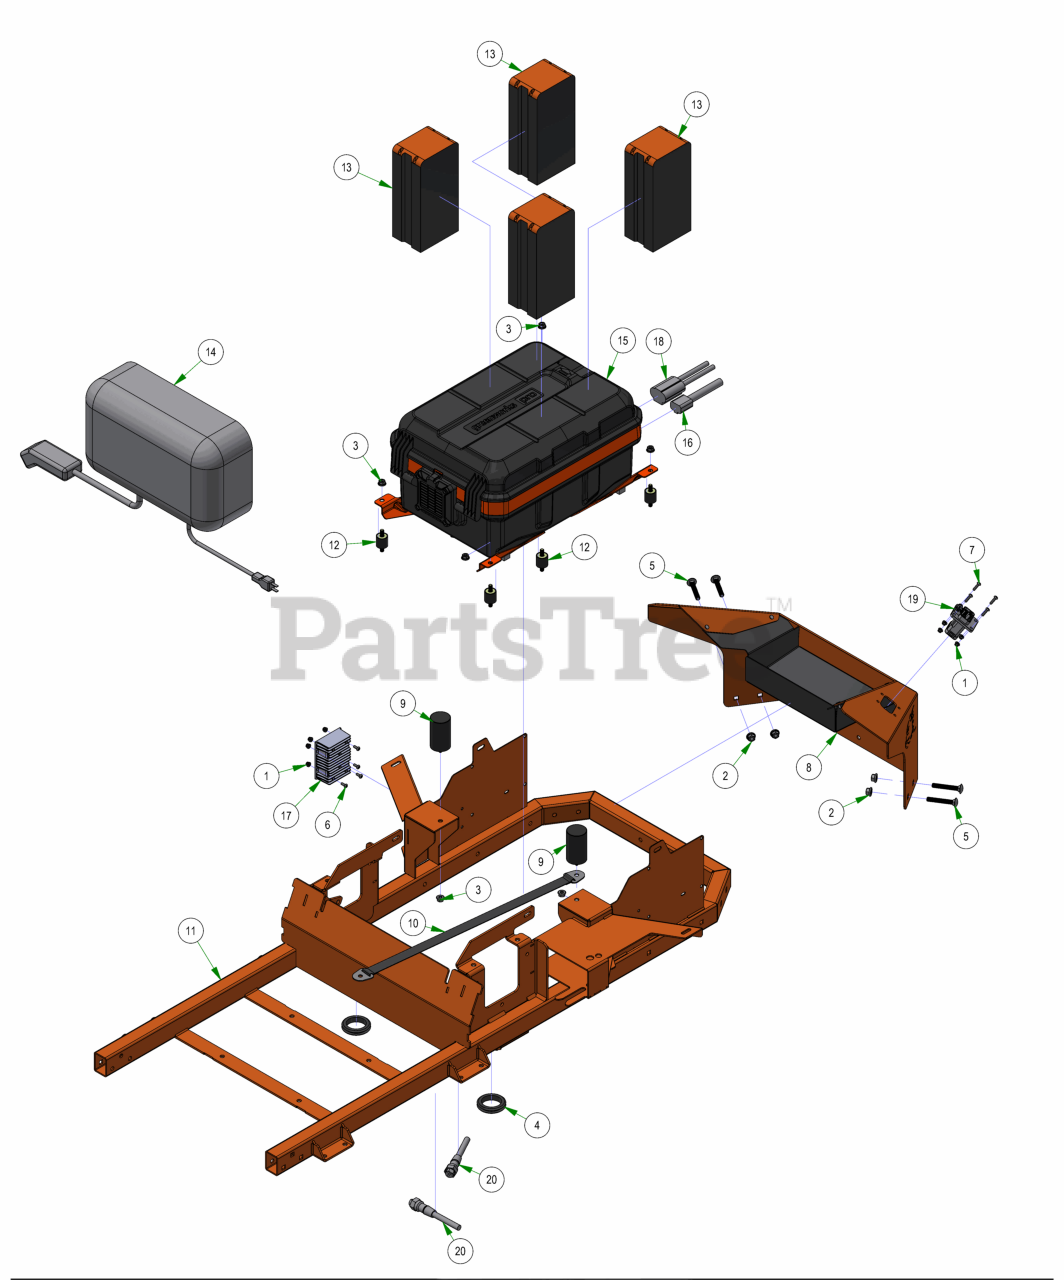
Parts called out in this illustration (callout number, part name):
1	10-24 NYLON INSERT LOCKNUT ZINC
2	3/8-16 NYLON INSERT FLANGE LOCKNUT (GR.F) ZINC
3	5/16-18 NYLON INSERT FLANGE LOCKNUT ZINC
4	2019 2" x .25 Rubber Grommet
5	3/8" x 2 1/2" Carriage Bolt
6	10-24 X 1/2 BUTTON SOCKET CAP SCREW 18-8 STAINLESS STEEL
7	10-24 X 3/4 BUTTON SOCKET CAP SCREW 18-8 STAINLESS STEEL
8	2024 EV Rear Plate Assembly
9	2019 Bad Boy X Cylindrical Seat Mount
10	Seat Strap with Buckles
11	Residential E Mower Frame
12	Vibration-Damping Sandwich Mount
13	Battery, 8.0 Ah
14	Charger, 80V
15	Residential E Mower Battery Pack
16	Control Harness Assembly of Whole Machine
17	Residential E Mower 12v Converter
18	Power Wiring Harness for Whole Machine
19	Residential E Mower Charge Port
20	Deck Control Harness
